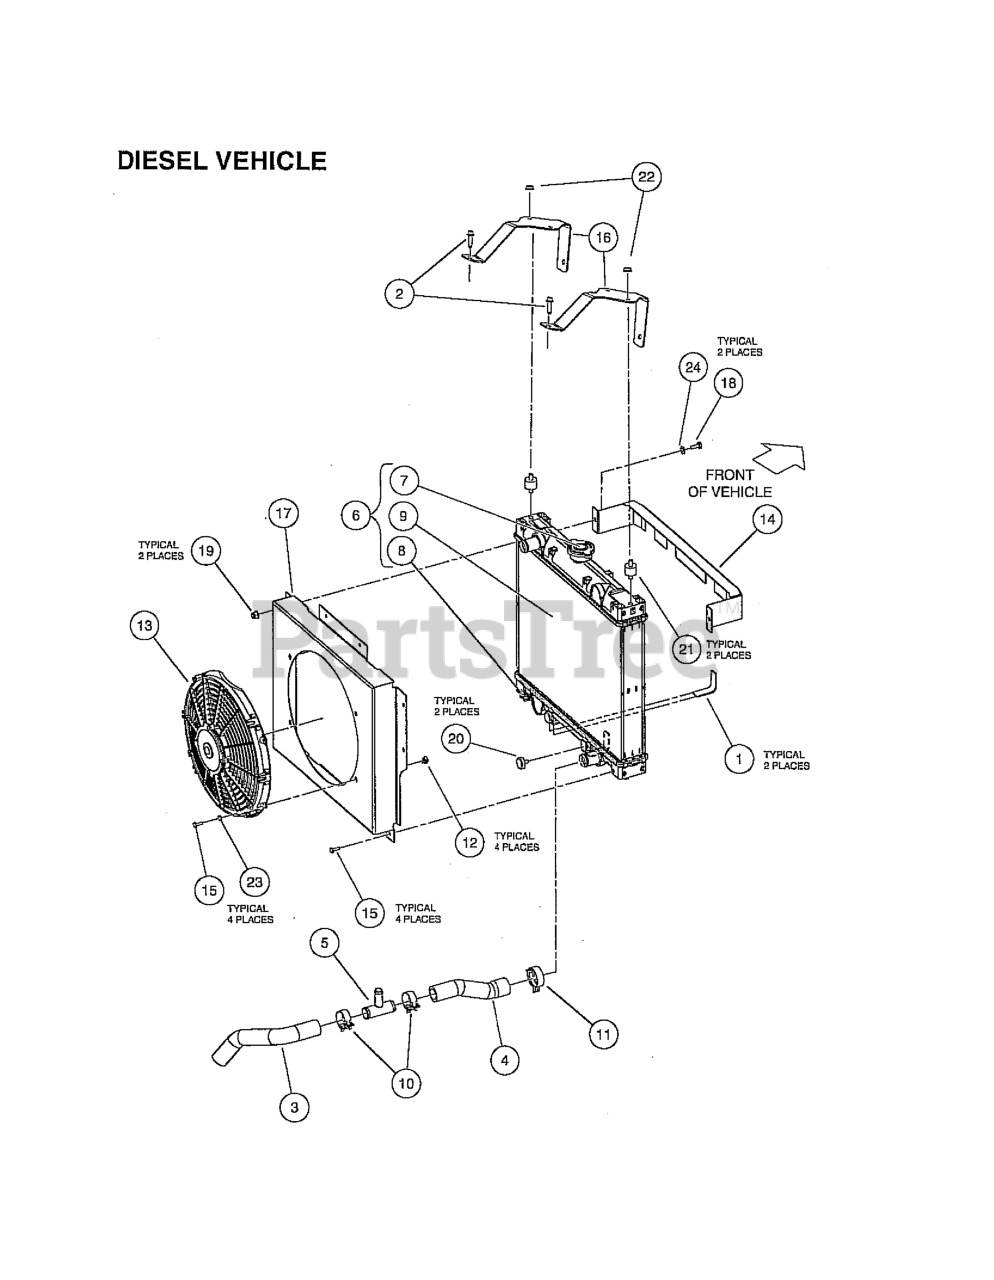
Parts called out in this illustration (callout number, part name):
1	BOX INS.BULK
2	SCREW-M8 X 1.25 30, TRI, HX F
3	HOSE, COOLANT LOWER PIPE
4	HOSE, COOLANT LOWER RAD
5	TEE, COOLANT FILL
6	EXCHANGER, ENGINE COOLANT
10	CLAMP, HOSE, CTB 35MM
11	CLAMP, HOSE, CTB 38MM
12	NUT, SELF RETAINING
13	FAN, COOLING 12 IN ELECT
14	GUARD, RADIATOR-TOP
15	BOLT, M6 X 1 X 16 LOCTITE
16	BRACKET, UPPER RADIATOR MOUNT
17	SHROUD, RADIATOR FAN
18	BOLT, M8 X 1.25 X 20
19	LOCK NUT, FLG M8 X 1.25 NYLON
20	BUMPER, 13MM STUD
21	ISOLATOR, TWIN STUD, RADIATOR
22	NUT FLG, M8 X 1.25 SERRATED
23	WASHER, M6
24	WASHER, M8 HARD
